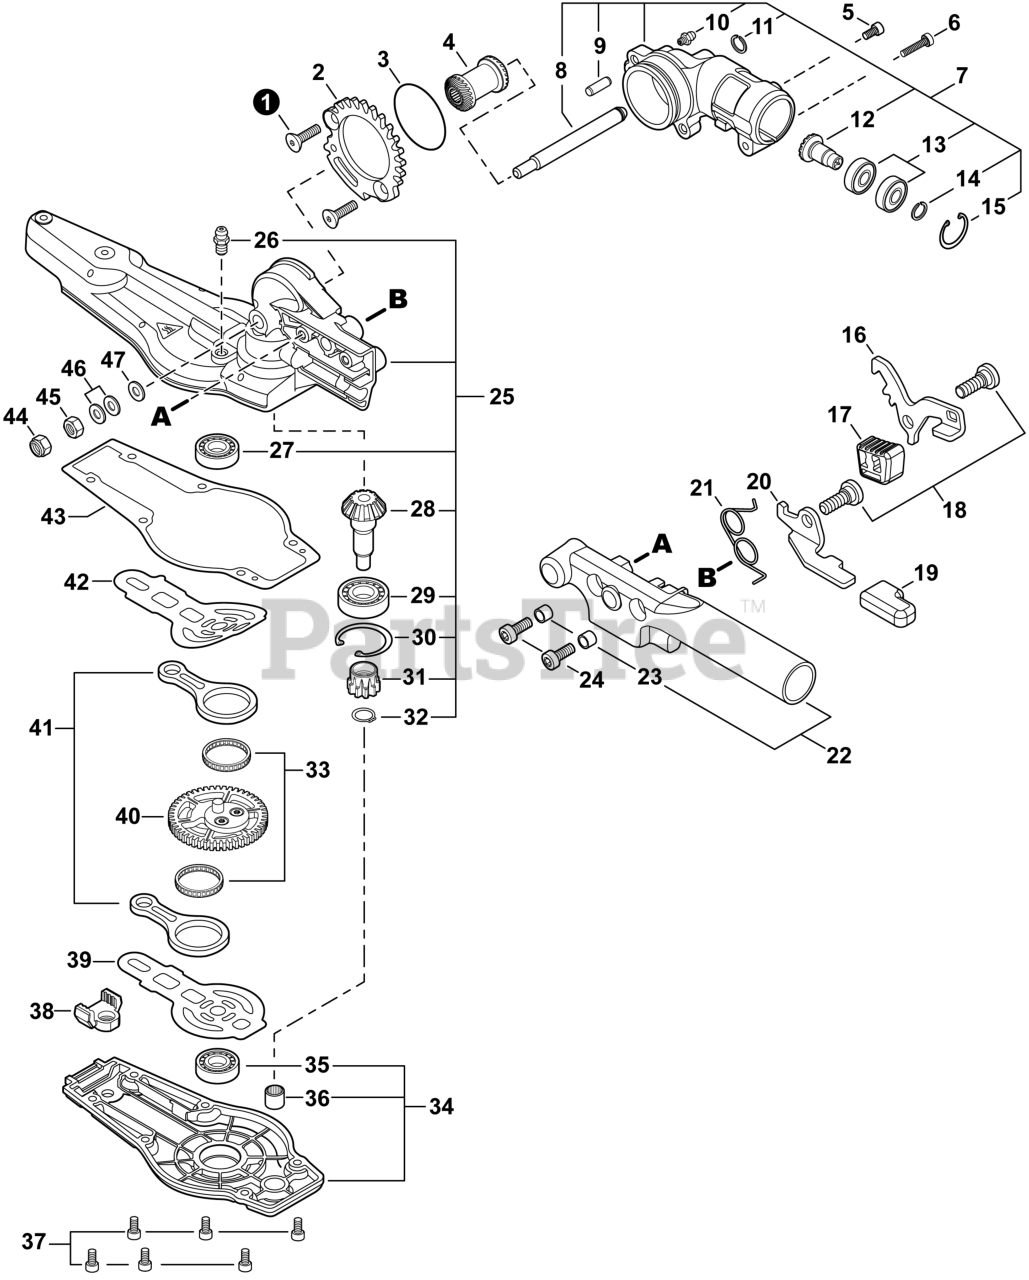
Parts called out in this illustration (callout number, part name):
1	BOLT 5x12
2	RING, LOCKING
3	O-RING 35
4	GEAR, BEVEL
5	BOLT, TORX 5x10
6	BOLT, TORX 5x25
7	GEAR CASE ASSY
8	SHAFT, GEAR
9	PIN 5 L15.5
10	FITTING, GREASE
11	E-RING 8
12	GEAR, BEVEL
13	BEARING, BALL 6901
14	RING, SNAP 12
15	RING, SNAP 24
16	LEVER, LOCK
18	BOLT M6
20	RELEASE, LOCK
21	SPRING, TORSION
22	LEVER, ADJUSTMENT
23	SPACER 6.2x7.8x6
24	BOLT, TORX 5x16
25	GEAR CASE ASSY
26	FITTING, GREASE
27	BEARING, BALL 608
28	SHAFT, PINION
29	BEARING, BALL 6001
30	RING, SNAP 28
31	GEAR, SPUR
32	RING, RETAINING 8
33	BEARING, NEEDLE 30
34	COVER ASSY, GEAR CASE
35	BEARING, BALL 608
36	BEARING, NEEDLE
37	BOLT, TORX 4x12
39	PLATE, WEAR
40	GEAR, SPUR
41	ROD, CONNECTING
42	PLATE, WEAR
43	GASKET, GEAR CASE
44	NUT, LOCK 6
46	WASHER, CONE M6
47	WASHER 6
